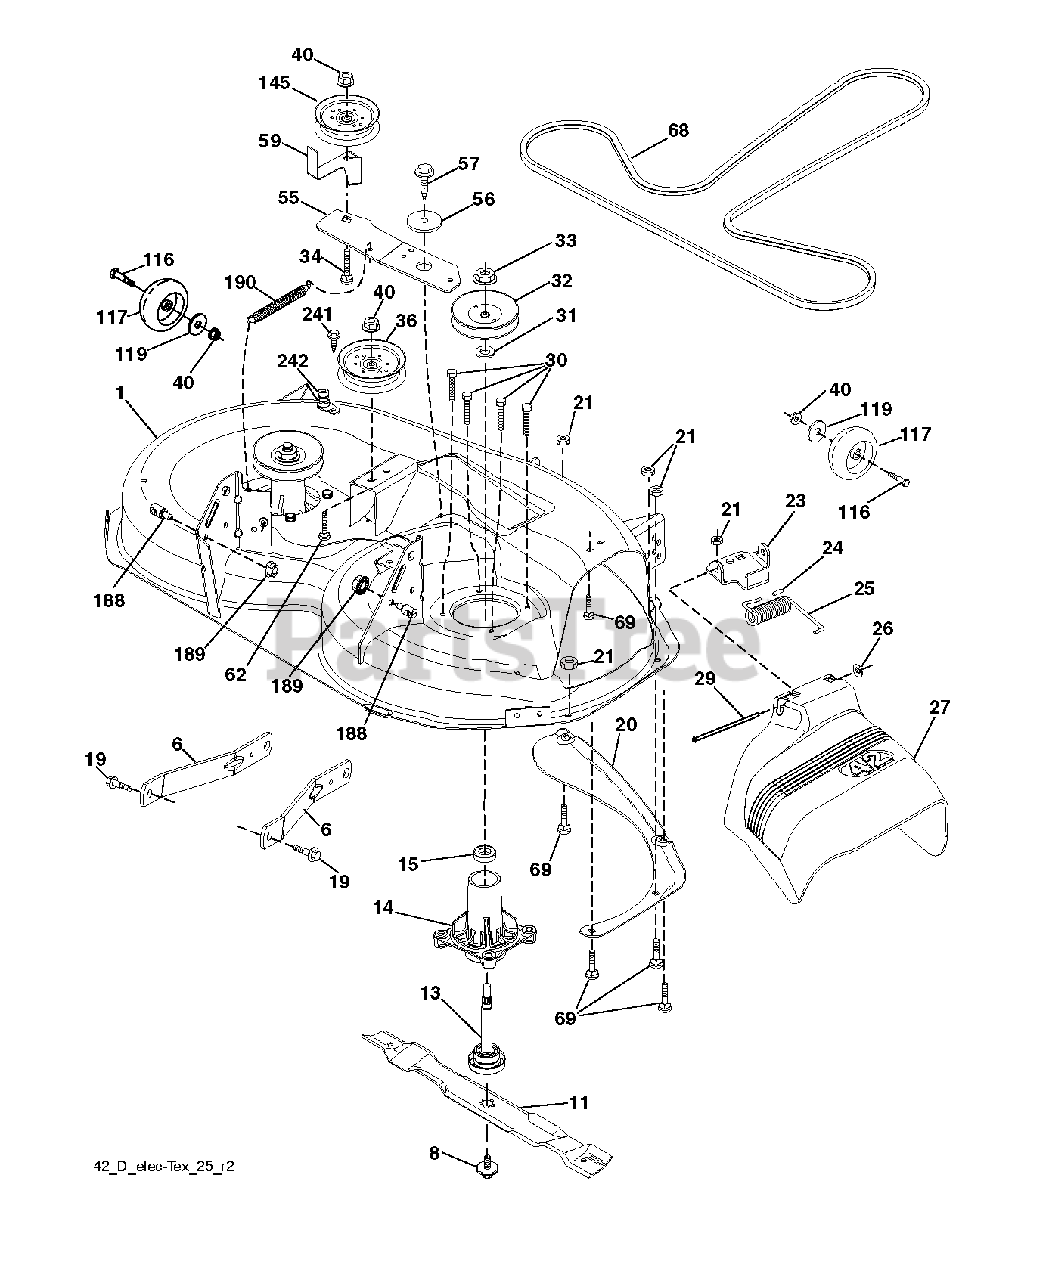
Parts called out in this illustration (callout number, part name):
1	DECK.WELDMNT.42"GREYMS498
6	ARM.SUSPENSION.MOWER.R
8	BOLT.WASHER.ASM.7/16-2
11	42" HI-LIFT BLADE
13	SHAFT.ASM.MDRL.N/GREASE.38
14	HOUSING.MANDREL.4PT.
19	BOLT.SHOULDER
20	BAFFLE.VORTEX
21	LOCKNUT
23	BRKT.DEFLECTOR.38"2005+
24	CAP-SLEEVE LT
25	SPRING.TORSION.DEFLECT
26	NUT PUSH M
27	SHIELD.DEFLECTOR.MOWER.42"BLAC
29	ROD.HINGE
30	SCREW, WASHER HEAD
31	WASHER.SPACER.MANDREL
32	PULLEY/MANDREL
33	NUT.FLANGE.LOCK.TOP
34	BOLT.3/8-16X1.50
36	PULLEY.IDLER.2006
40	NUT LOCK FLG 3/8-16 UNC
55	IDLER.ARM.42"
56	SPACER.RETAINER
57	SCREW 3/8-16X1
59	GUARD, BELT
68	BELT V SECONDARY
69	BOLT
116	BOLT M
117	WHEEL.GAGE.HALF.SPOKED
119	WASHER
145	PULLEY.IDLER.48"PRIMARY
188	STUD.FASTNER.W/ANTI-ROTATE
189	NUT LOCK HEX FLANGE 5/16-18
190	SPRING.MOWER.DRIVE.ELECTRIC
241	SCREW.TT.#10-32X.5.3/8.FLANGE
242	PORT.WASHOUT
